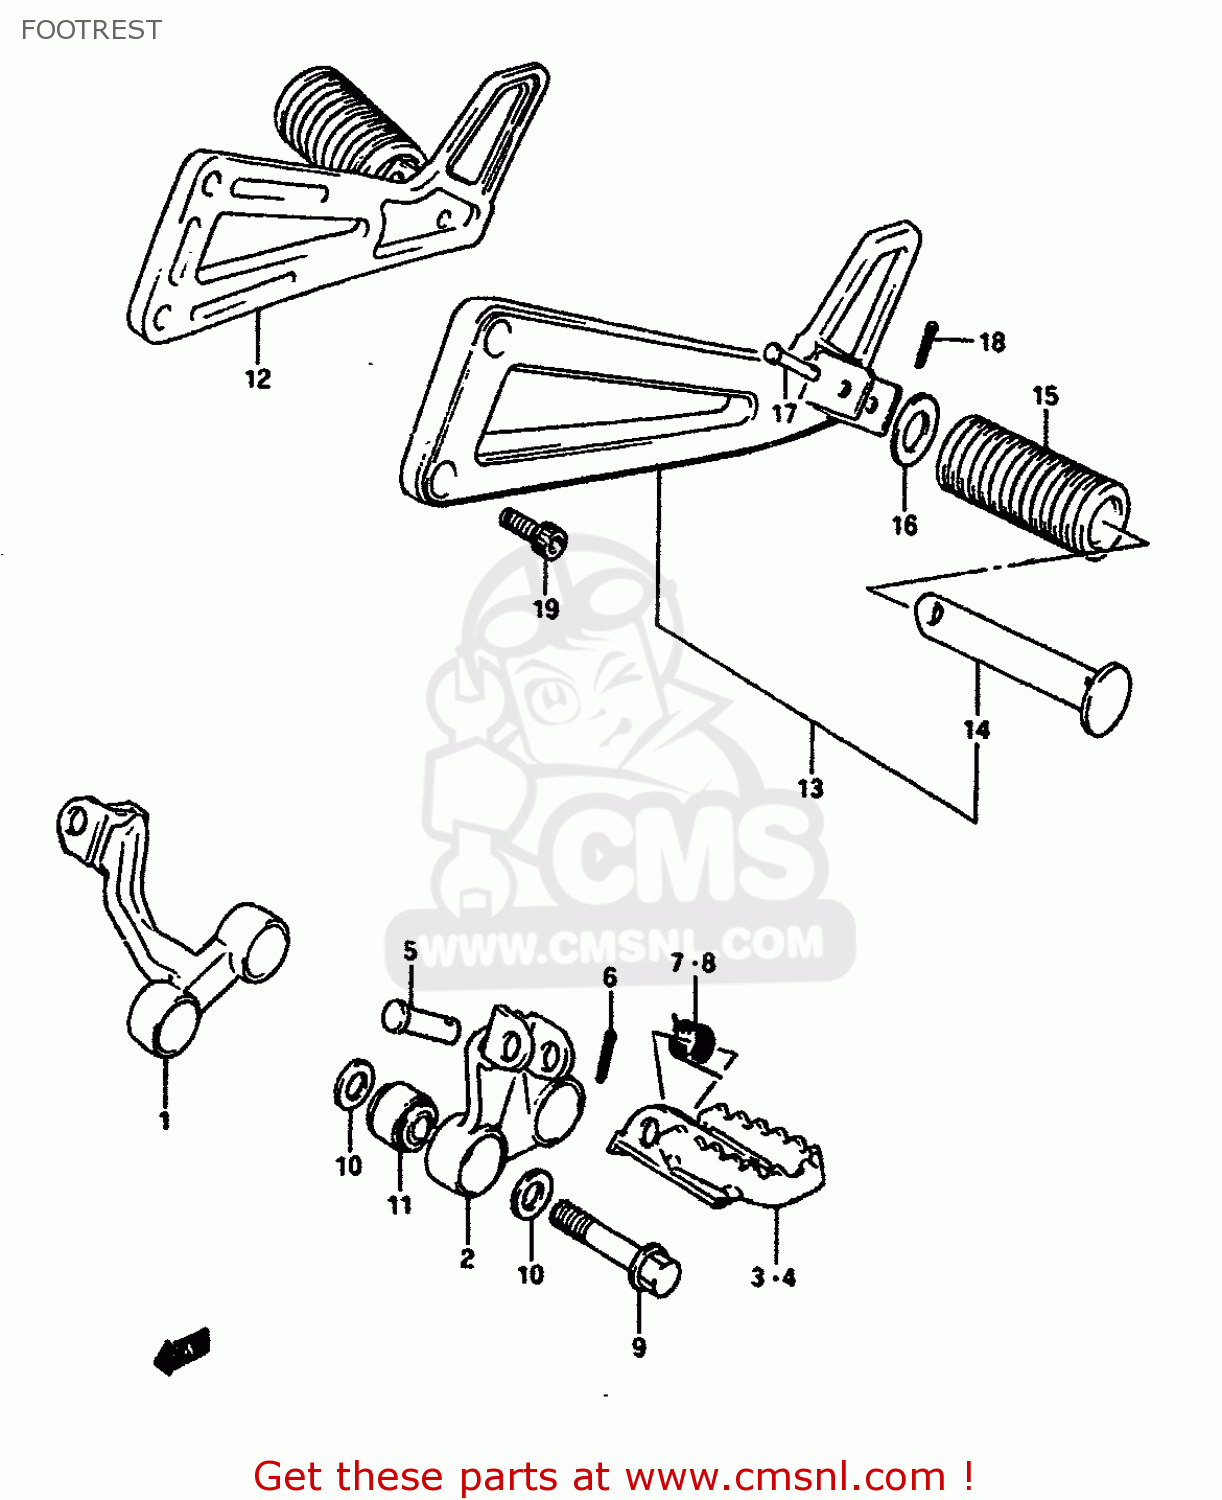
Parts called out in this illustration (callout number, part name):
1	BAR,FR FOOTREST,R
2	BAR,FRONT FOOTREST,LEFT
3	FOOTREST,FR,R
4	FOOTREST,FR,L
5	PIN
6	PIN 20X20
7	SPRING
8	SPRING
9	BOLT(10X50)
10	WASHER
11	BUSH(10.2X25X19)
12	FOOTREST,PILLION RH
13	FOOTREST,PILLION
14	BAR,FOOTREST RUBBER
15	RUBBER,PILLION FOOTREST
16	WASHER (19.5X32X2)
17	PIN
18	PIN
19	BOLT
